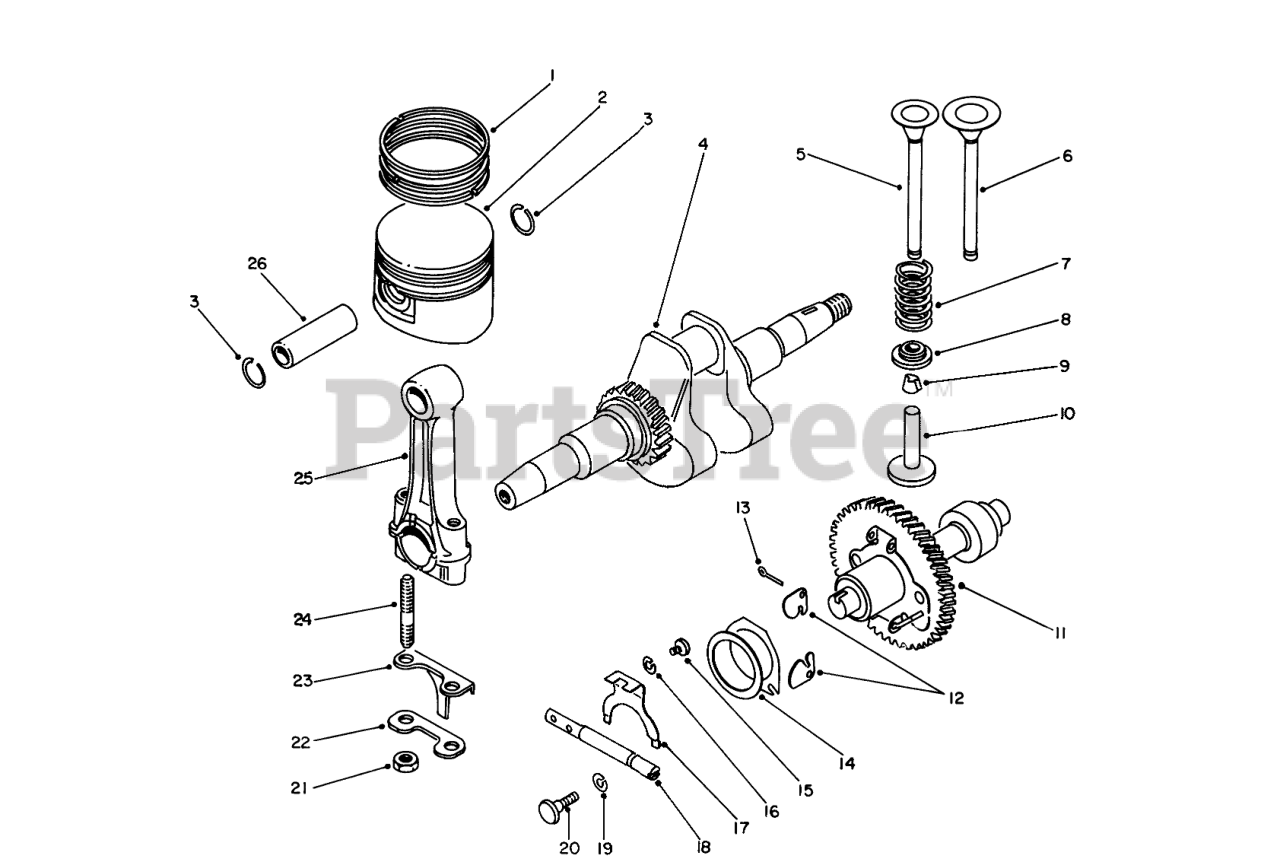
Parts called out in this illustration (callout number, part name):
1	RING SET
2	Piston
3	Circlip
4	Crankshaft
5	EXHAUST VALVE
6	Valve-Intake
7	Spring
8	Retainer
9	Cotter
10	Tappet
11	Camshaft
13	Cotter Pin
14	Spacer
15	Screw
16	Lockwasher
17	PLATE
18	Shaft
19	Gasket
20	Screw
22	LOCK PLATE
23	Plate-Splash
25	Rod-Connecting (Incl. Ref. #21-214)
26	PISTON PIN
